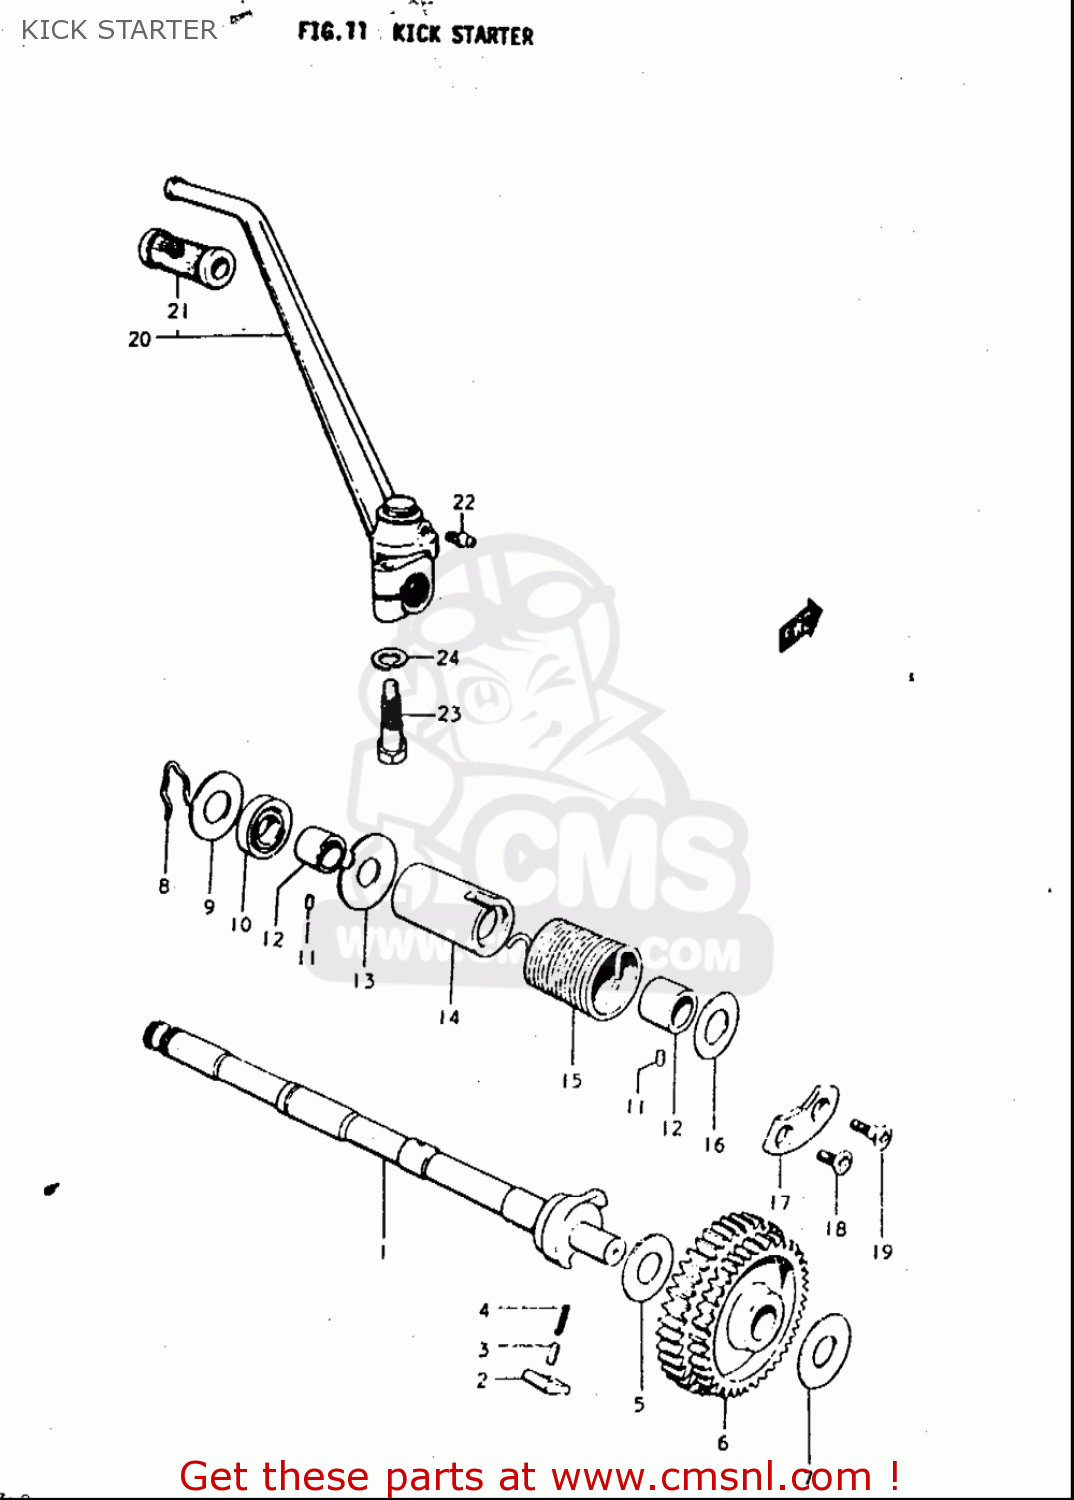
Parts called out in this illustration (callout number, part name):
3	PIN(5X15.5)
4	SPRING
5	WASHER(13X31.5X1.5)
7	WASHER(13X31.5X1.5)
10	SEAL,OIL(16X30X8)
11	PIN
15	SPRING
16	WASHER(16X30X1)
18	SCREW
19	SCREW(6X19)
21	RUBBER,KICK STARTER PEDAL
22	NIPPLE
23	BOLT(10X37.5)
24	WASHER,LOCK
